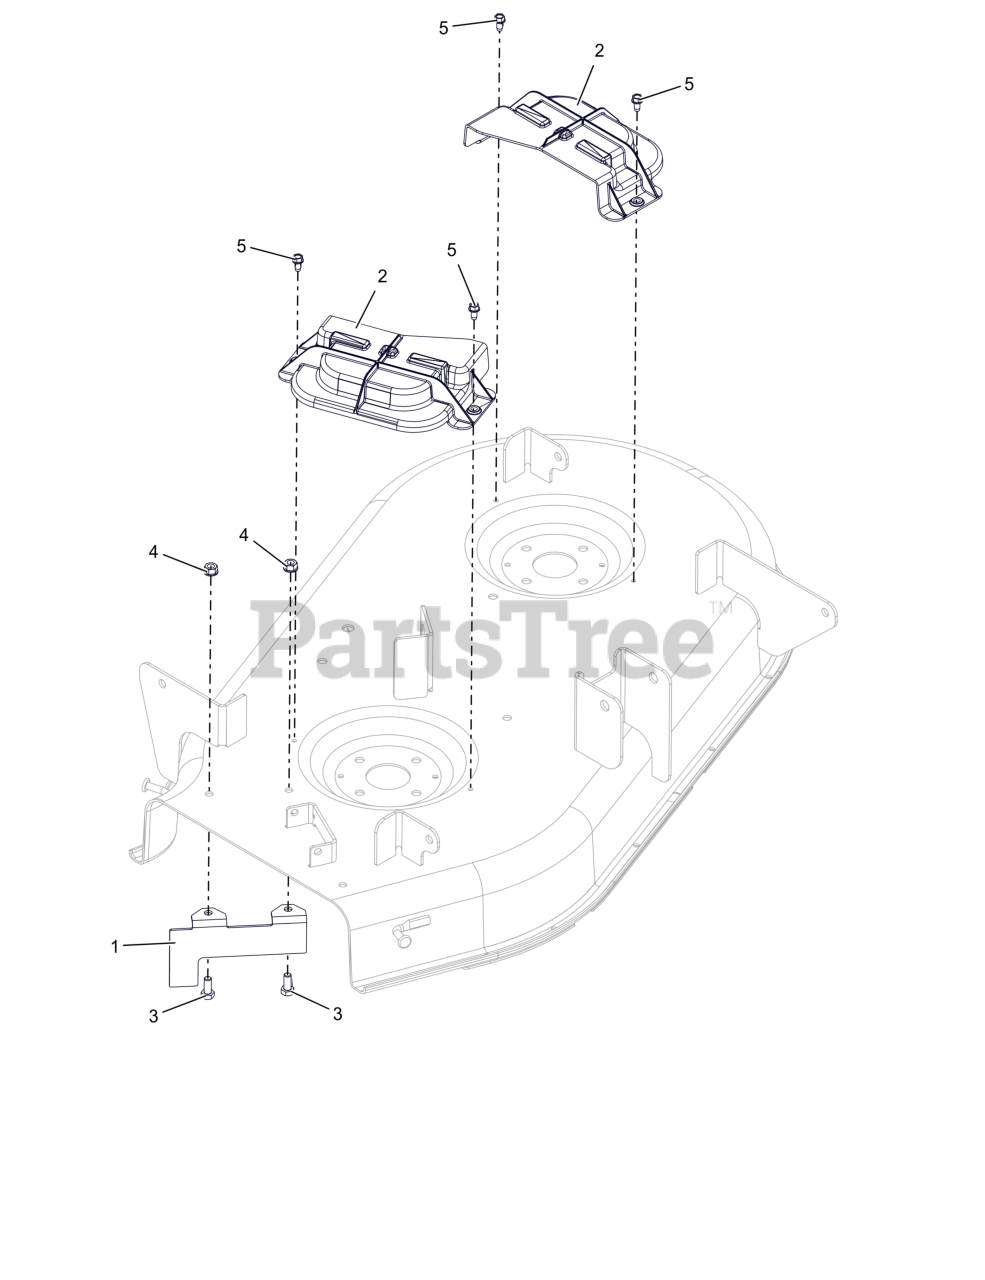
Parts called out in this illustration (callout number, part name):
1	BRKT-BAFFLE, DISCHARGE 34"
2	COVER-BELT, MOLDED
3	BLT,HEX .31-18X.75 G5 ZCC
4	NUT,LK-CTR-FLG .31-18 GF ZCC
5	SCR-TAP .25-20X.50 HWH ZCC
